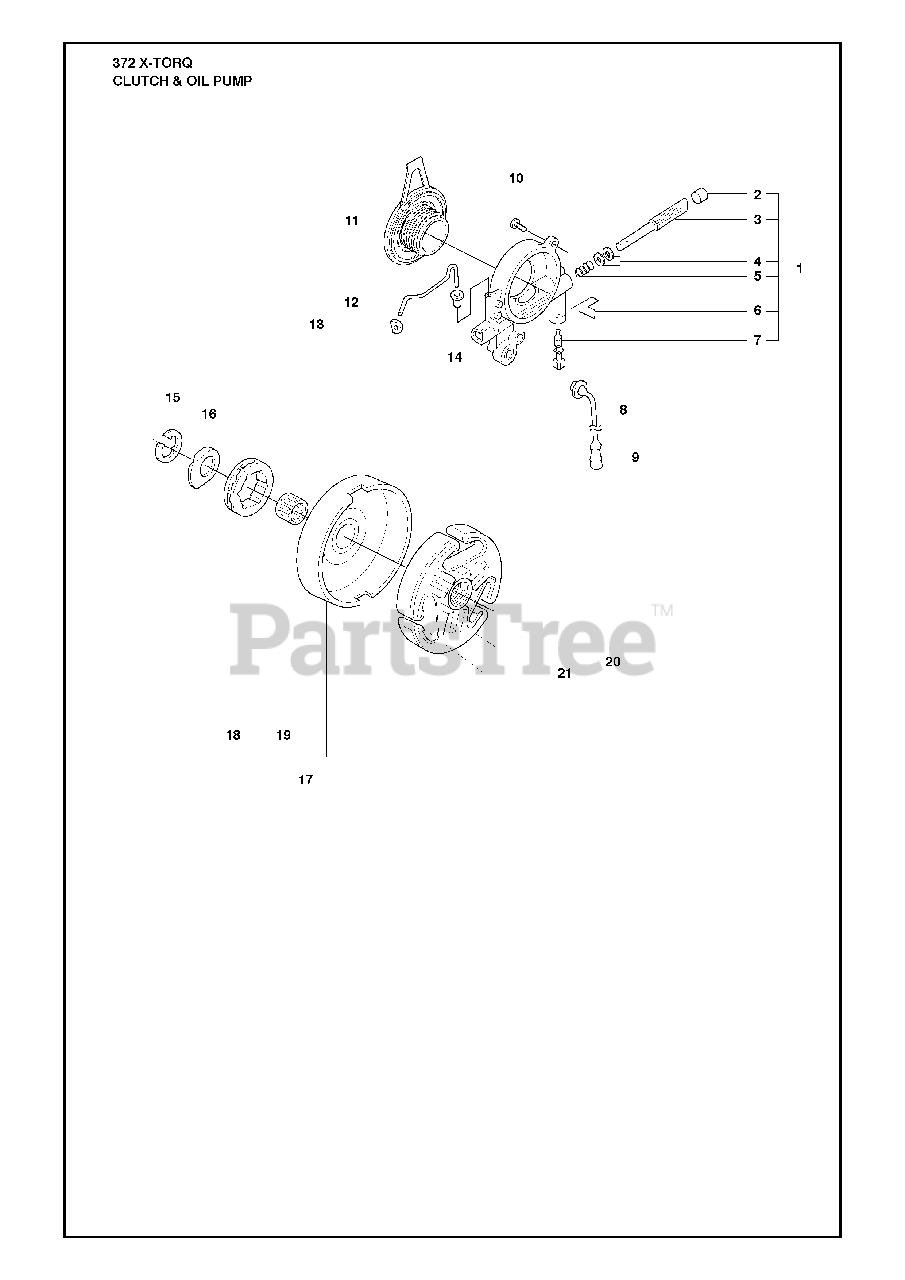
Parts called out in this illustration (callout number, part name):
1	OIL PUMP
3	PUMP PISTON
4	WASHER 6.1X9
6	SPRING CLIP
9	OIL SCREEN
10	SCREW MC6S 5X16
11	OIL PUMP DRIVE
15	RETAINING RING
17	CLUTCH DRUM
18	68210 RIMSPROCKET
18	Power Mate Rim
19	CLUTCH DRUM BEARING
20	CLUTCH
21	CLUTCH SPRING
